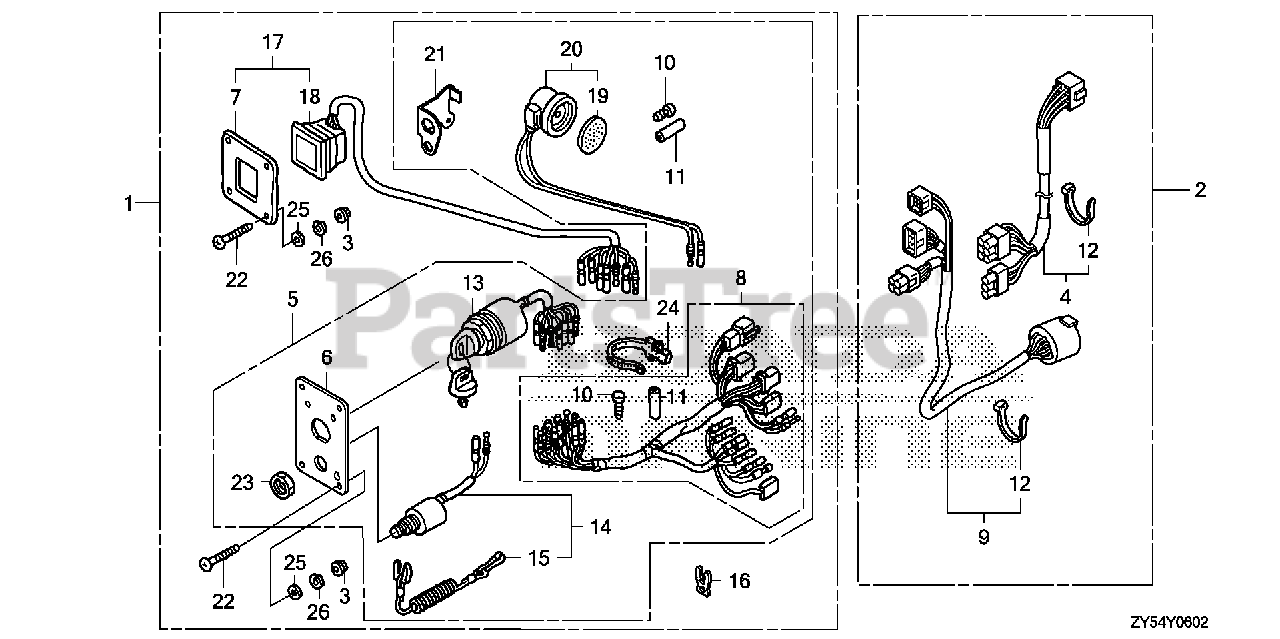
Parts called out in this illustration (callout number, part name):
1	PANEL KIT, SWITCH (4-LED) (B)
2	CABLE SET, PANEL INDICATOR (20FT)
2	CABLE SET, PANEL INDICATOR (25FT)
2	CABLE SET, PANEL INDICATOR (30FT)
3	NUT, FLANGE (5MM) DUAL QTY = (8) (SINGLE)
4	WIRE ASSY., INDICATOR (20FT)
4	WIRE ASSY., INDICATOR (25FT)
4	WIRE ASSY., INDICATOR (30FT)
5	PANEL ASSY., SWITCH
6	PANEL, CONTROL
7	PANEL, CONTROL
8	HARNESS ASSY., SWITCH PANEL
9	CABLE ASSY., SWITCH PANEL (20FT) (NHK MEC)
9	CABLE ASSY., SWITCH PANEL (25FT) (NHK MEC)
9	CABLE ASSY., SWITCH PANEL (30FT) (NHK MEC)
9	CABLE ASSY., SWITCH PANEL (30FT) (FOR 4-LED)
10	PLUG, CONNECTOR (INNER) (TROLLING CONTROL)
11	PLUG, CONNECTOR (OUTER) (ENGINE NO.)
12	TIE, CABLE (NATURAL 2.4X92) Use up to Frame SN 1300359.
13	SWITCH ASSY., COMBINATION (SINGLE) (DUAL)
14	SWITCH ASSY., EMERGENCY STOP
15	WIRE, EMERGENCY (SINGLE) (DUAL)
16	CLIP, EMERGENCY LOCK
17	PANEL ASSY., INDICATOR (4-LED)
18	LAMP ASSY., INDICATION (4-LED)
19	PLATE, TURN SIGNAL BUZZER DUAL QTY = (2) (SINGLE)
20	BUZZER, WARNING DUAL QTY = (2) (SINGLE)
21	BRACKET, BUZZER
22	SCREW, PAN (5X40) DUAL QTY = (8) (SINGLE)
23	NUT, HEX. (16MM) DUAL QTY = (2) (SINGLE)
24	BAND, WIRE HARNESS (150MM) (NATURAL) DUAL QTY = (2) (SINGLE)
25	WASHER, PLAIN (5MM) DUAL QTY = (8) (SINGLE)
26	WASHER, SPRING (5MM) DUAL QTY = (8) (SINGLE)
